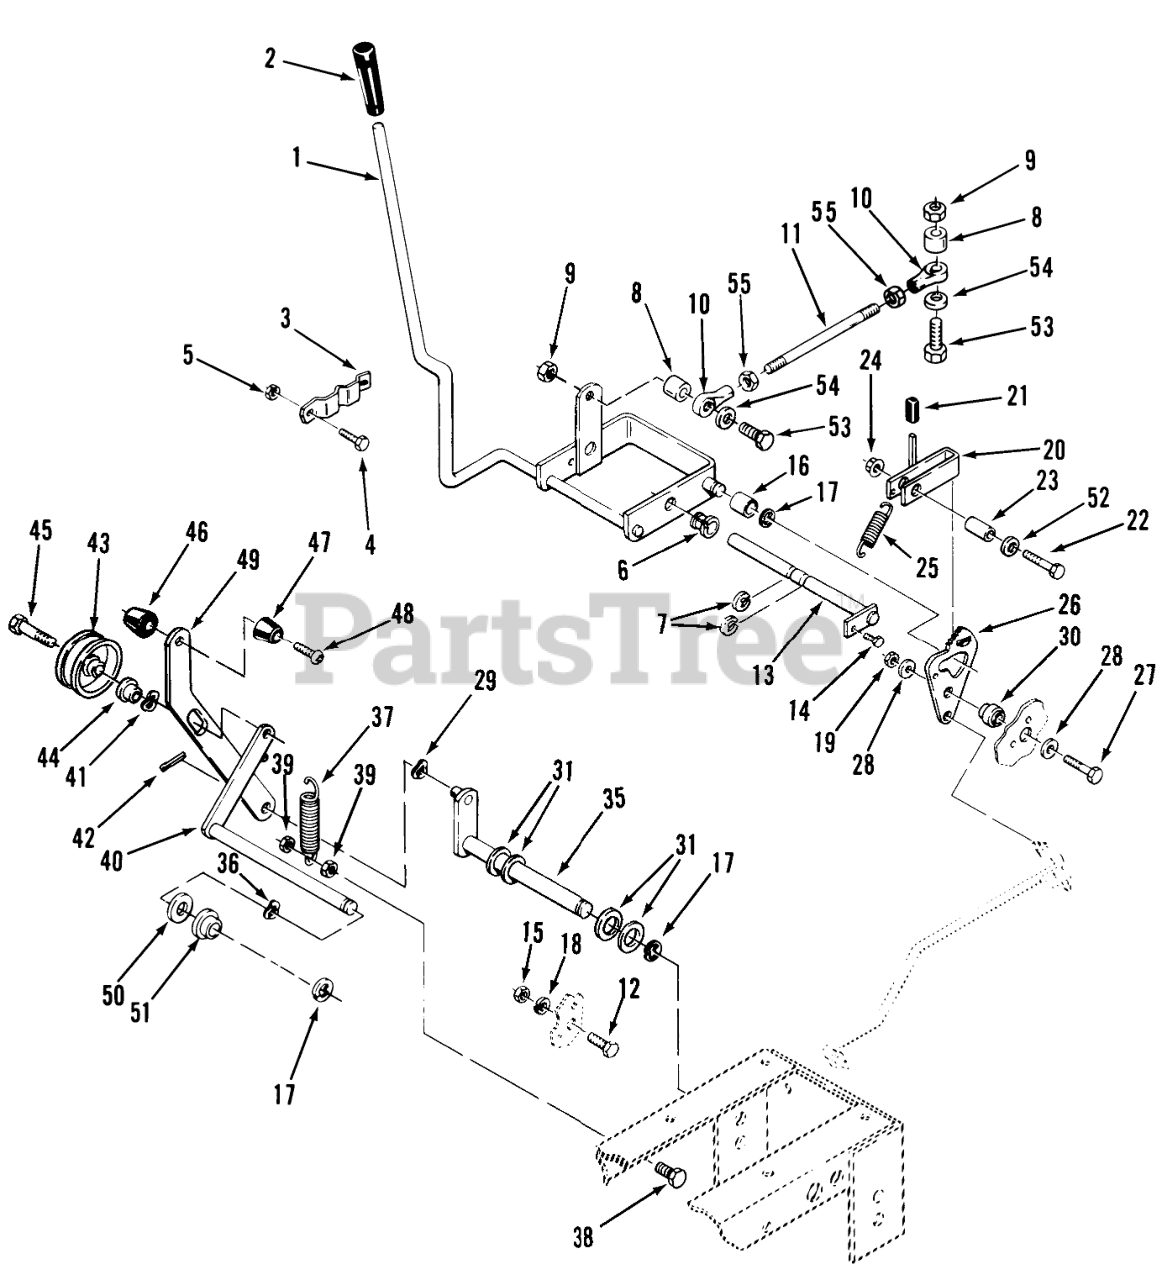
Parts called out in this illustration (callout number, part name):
1	Motion Control Lever
2	KNOB
3	Detent-Motion Control Lever
4	H H C S
5	Nut
6	NYLINER BUSHING
7	E Ring
8	Spacer
9	Nut
10	ASSY ROD END
11	ROD-CONTROL
12	Bolt
13	ASSY-ROD CAM PIVOT
14	SCREW
15	Nut
16	BEARING-CAM RETURN
17	E Ring
18	LOCKWASHER
19	Nut
20	PAWL HDL ASSY B
21	VALVE LEVER GRIP
22	Bolt
23	SPACER
24	LOCKNUT-FLANGE
25	Spring
26	Cam Plate
27	Bolt
28	Washer
29	WASHER-WAVE
30	Spacer
31	Washer
35	ASSY-BRAKE LEVER
36	WASHER-WAVE
37	SPRING-EXTENSION
38	Bolt
39	Nut
40	ASSY-ARM/ROD WA
41	WAVE WASHER
42	Cotter Pin
43	Idler Pulley
44	SPACER-BRAKE LINK
45	BOLT-SPECIAL HEX
46	KNOB
47	KNOB
48	BOLT-4
49	Handle
50	Washer
51	BUSHING-FLANGED
52	Washer
53	Bolt 1/4-20 X 1 1/2
55	Jam Nut 1/4-28
